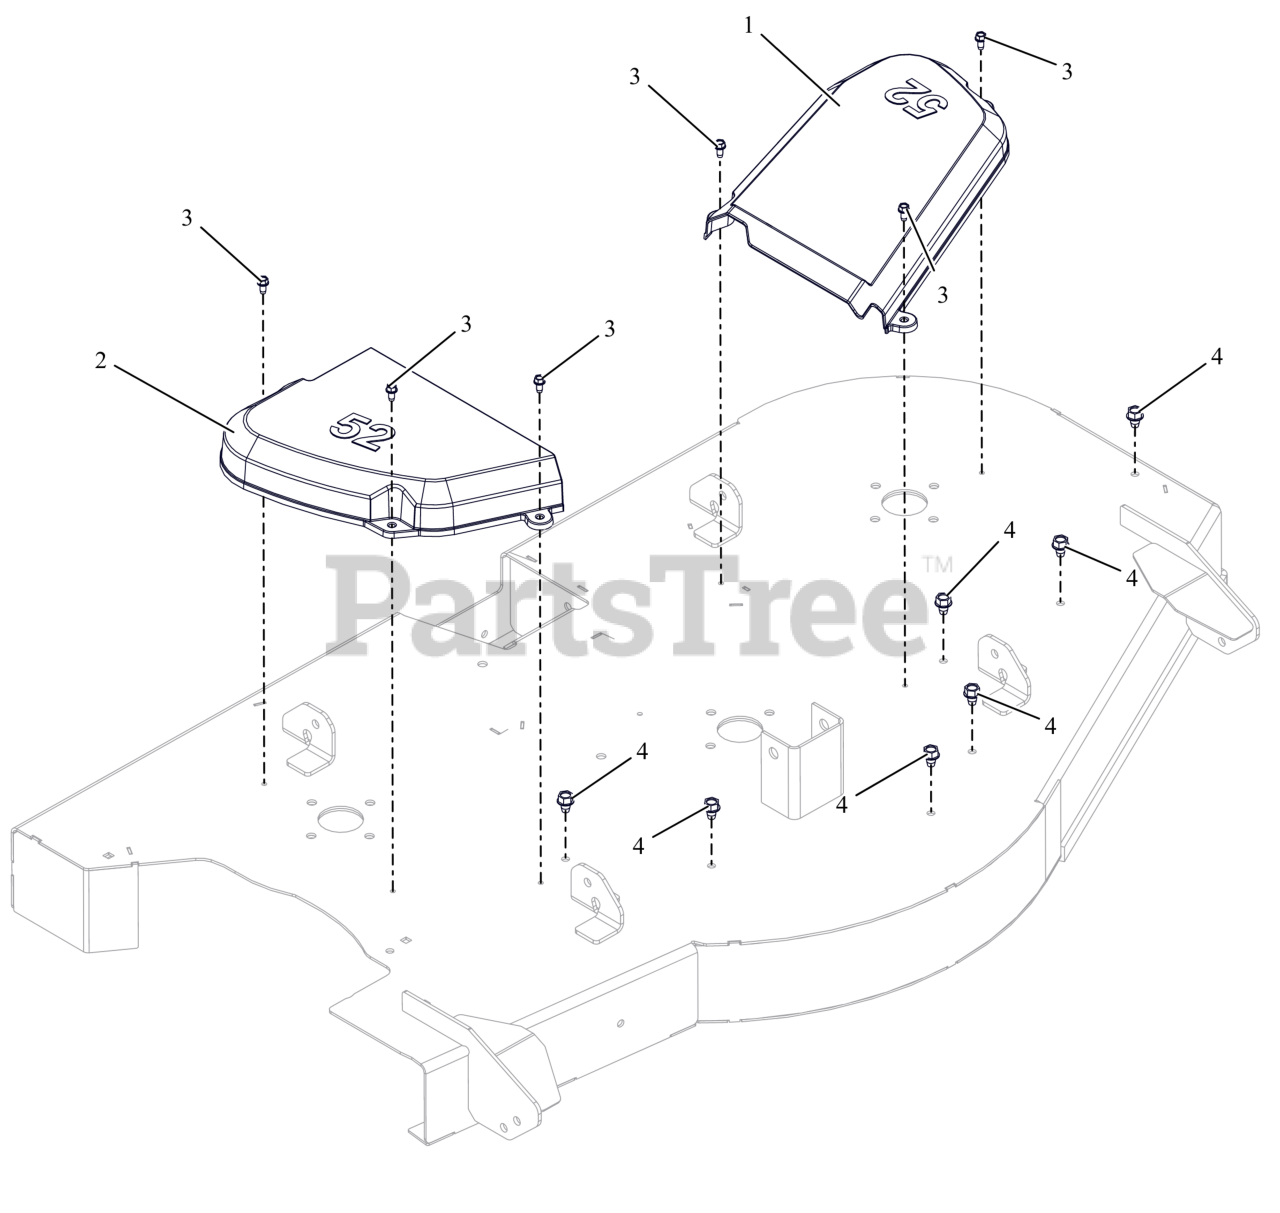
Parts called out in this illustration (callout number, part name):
1	COVER, BELT 52" LH-EDGE
2	COVER, BELT 52" RIGHT-EDGE
3	SCR-TAP .25-20X.50 HWH ZCC
4	SCR,TAP .375-16X.50 HWH TR ZCC
